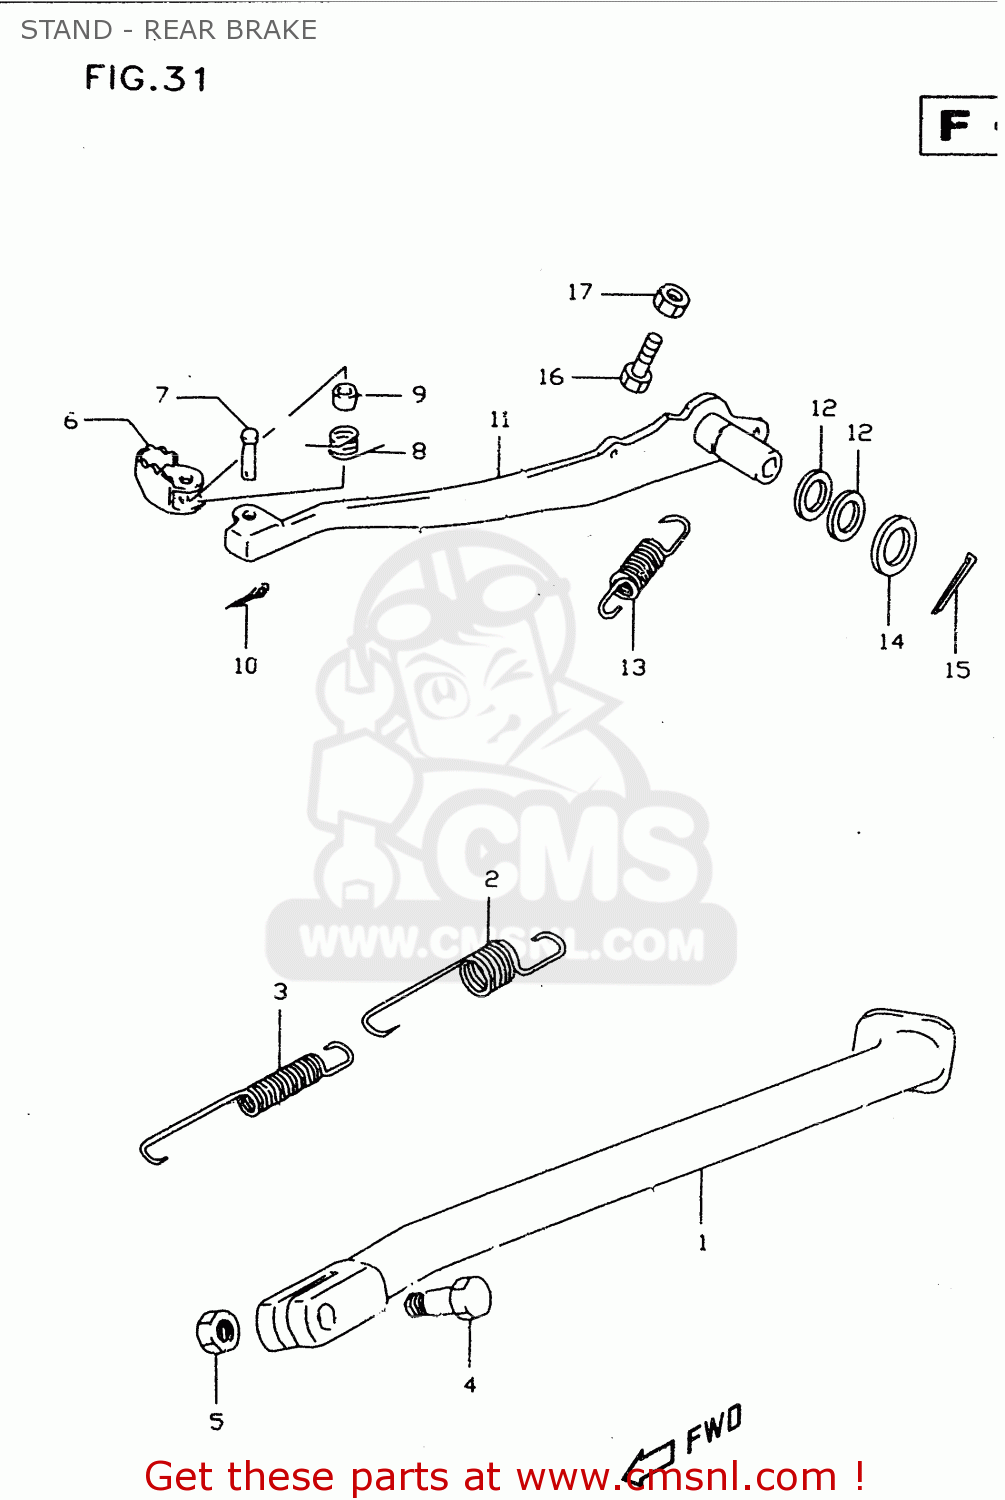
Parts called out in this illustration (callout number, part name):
1	STAND,PROP
2	SPRING
3	SPRING
4	BOLT(10X30)
5	NUT
6	PEDAL,BRAKE
7	PIN
8	SPRING
9	SPACER(6.5X9X6.5)
10	PIN
11	ARM,BRAKE PEDAL
12	SEAL,OIL(15X21X3)
13	SPRING
14	WASHER(15.5X26X2.3)
15	COTTER PIN
16	BOLT(6X23)
17	NUT 6MM
